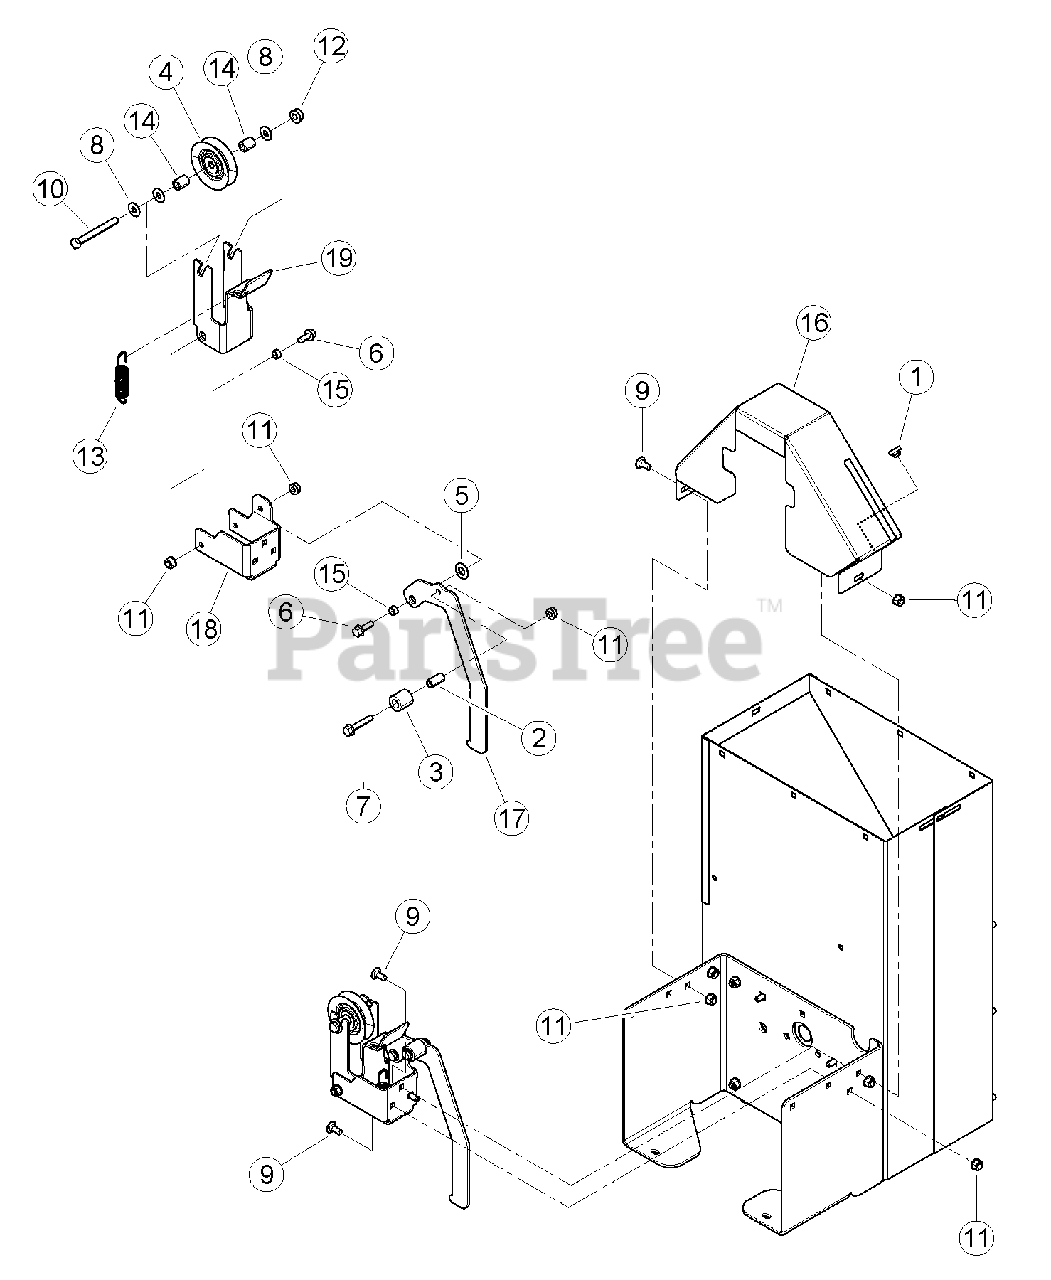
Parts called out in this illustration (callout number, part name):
1	BUMPER, RUBBER
2	SPACER, 0.5 X 1.00
3	ROLLER, 0.5 X 1.00 X 1.00 NYLON
4	IDLER, INSIDE
5	WASHER, 1/2 INCH NYLON
6	BOLT, 5/16 X 7/8 FLANGE NC
7	BOLT, 5/16 X 1-3/4 FLANGE NC
8	WASHER, 5/16" FLAT ZP
9	BOLT, 5/16 X 3/4 GR5 CRG NC ZP
10	BOLT, 3/8 X 3-1/4 HEX HD GR5 ZP
11	NUT, 5/16-18 NYLOCK FLANGE
12	NUT, 3/8-16 NYLOCK FLANGE
13	SPRING, 3/4" OD EXTENSION
14	SPACER, 3/4" LONG IDLER TUBE
15	SPACER, .50 X .25
16	SHIELD, UPPER
17	HANDLE, ENGAGEMENT
18	MOUNT, IDLER BRACKET
19	BRACKET, IDLER 3 IN CHIPPER
